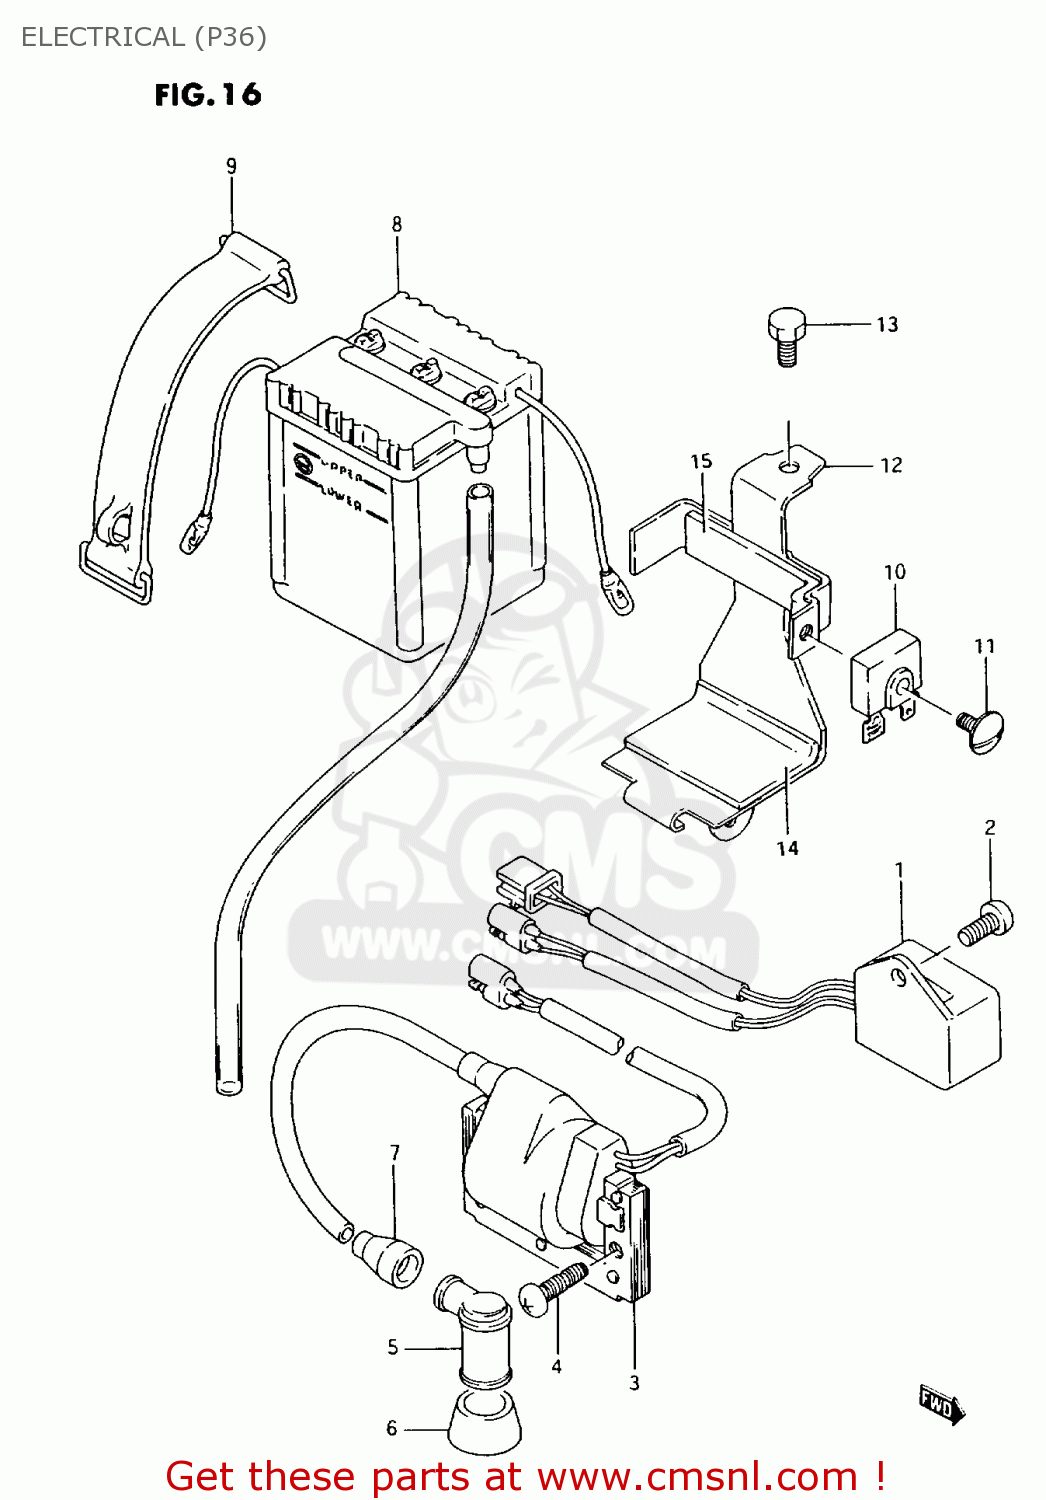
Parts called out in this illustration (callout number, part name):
1	CDI UNIT
2	SCREW
3	COIL ASSY,IGNITION
4	SCREW(6X21)
5	CAP ASSY,SPARK PLUG
6	SEAL,SPARK PLUG
7	SEAL,HIGH TENSION CORD
8	BATTERY ASSY(6N4-2A4.2AH)
9	BAND,BATTERY
10	RECTIFIER ASSY
11	SCREW(5X18)
12	HOLDER,BATTERY
13	BOLT
14	PROTECTOR(170X95X3.0)
15	PROTECTOR(170X95X3.0)
